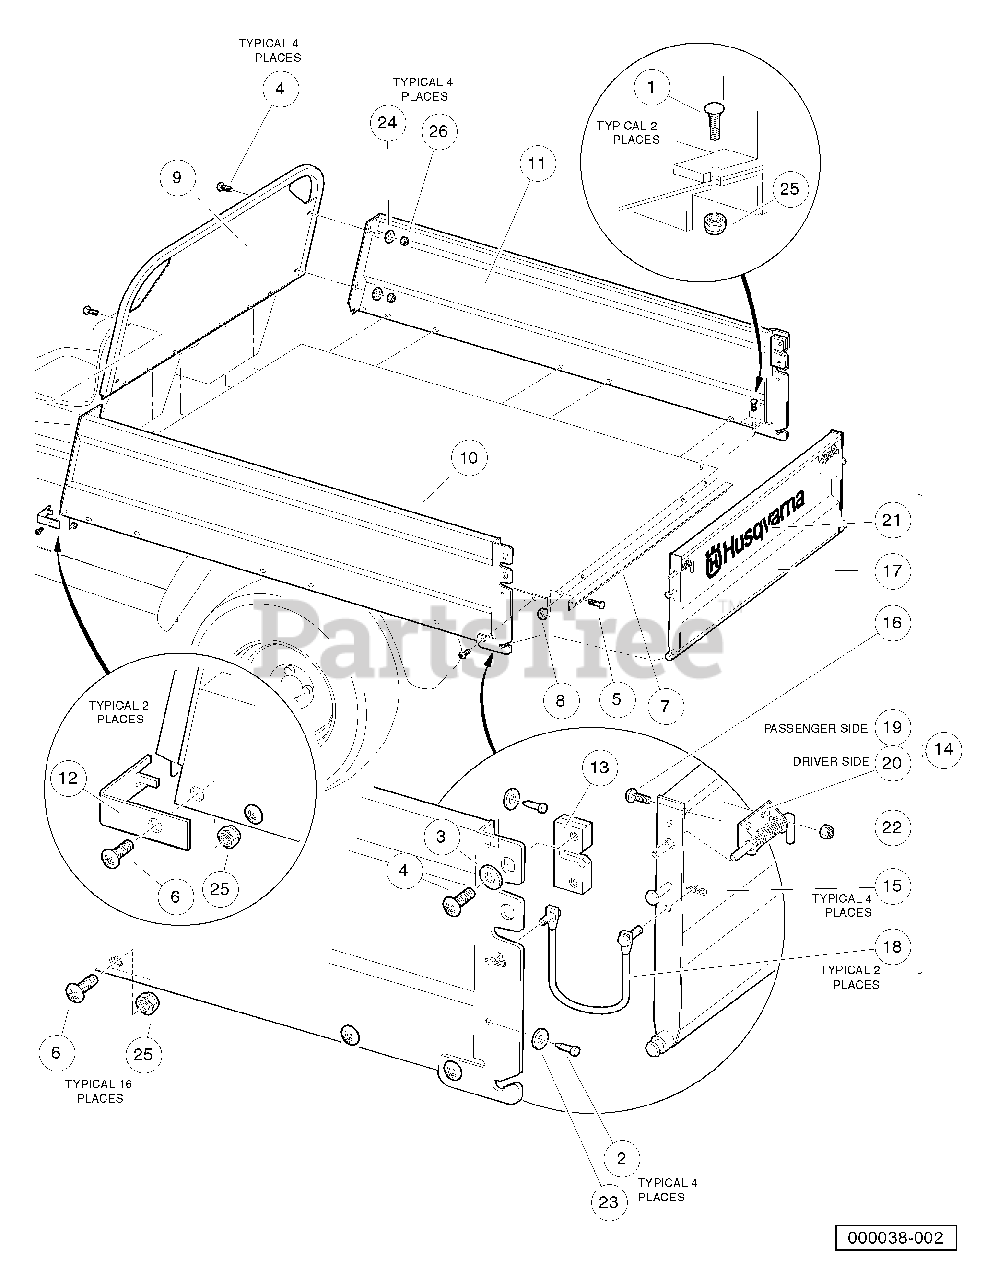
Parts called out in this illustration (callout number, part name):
1	Bolt, Carriage, 5/16-18 X 1.00
2	Bumper, Rubber
3	Washer, 1/4" Type B Flat
4	Screw, 1/4-20 X 0.75 Torx Truss-Head
5	Stud, Self-Clinching Flush Head
6	Screw, 5/16-18 X 0.88 Torx Truss-Head
7	Box Bed Tailgate Angle
8	Locknut, 5/16-18 Hex Flange
9	Front Panel Weldment
10	Left Panel Weldment
11	Right Panel Weldment
12	Front Corner Cap
13	Slam Latch
14	Assembly, Tailgate
15	Hair Pin Clip
16	Screw, 1/4-20 X 0.75 Torx Truss-Head
17	Tailgate, Weldment
18	Tether Assembly
19	Spring Latch Left
20	Spring Latch Right
21	Decal, Husqvarna, Tailgate
22	Locknut, 1/4-20 Nylon Insert
23	Washer, Rubber, 3/8
24	Washer, 1/4 Type A Narrow Flat
25	Locknut, 5/16-18 Nylon Insert
26	Locknut, 1/4-20 Nylon Insert
